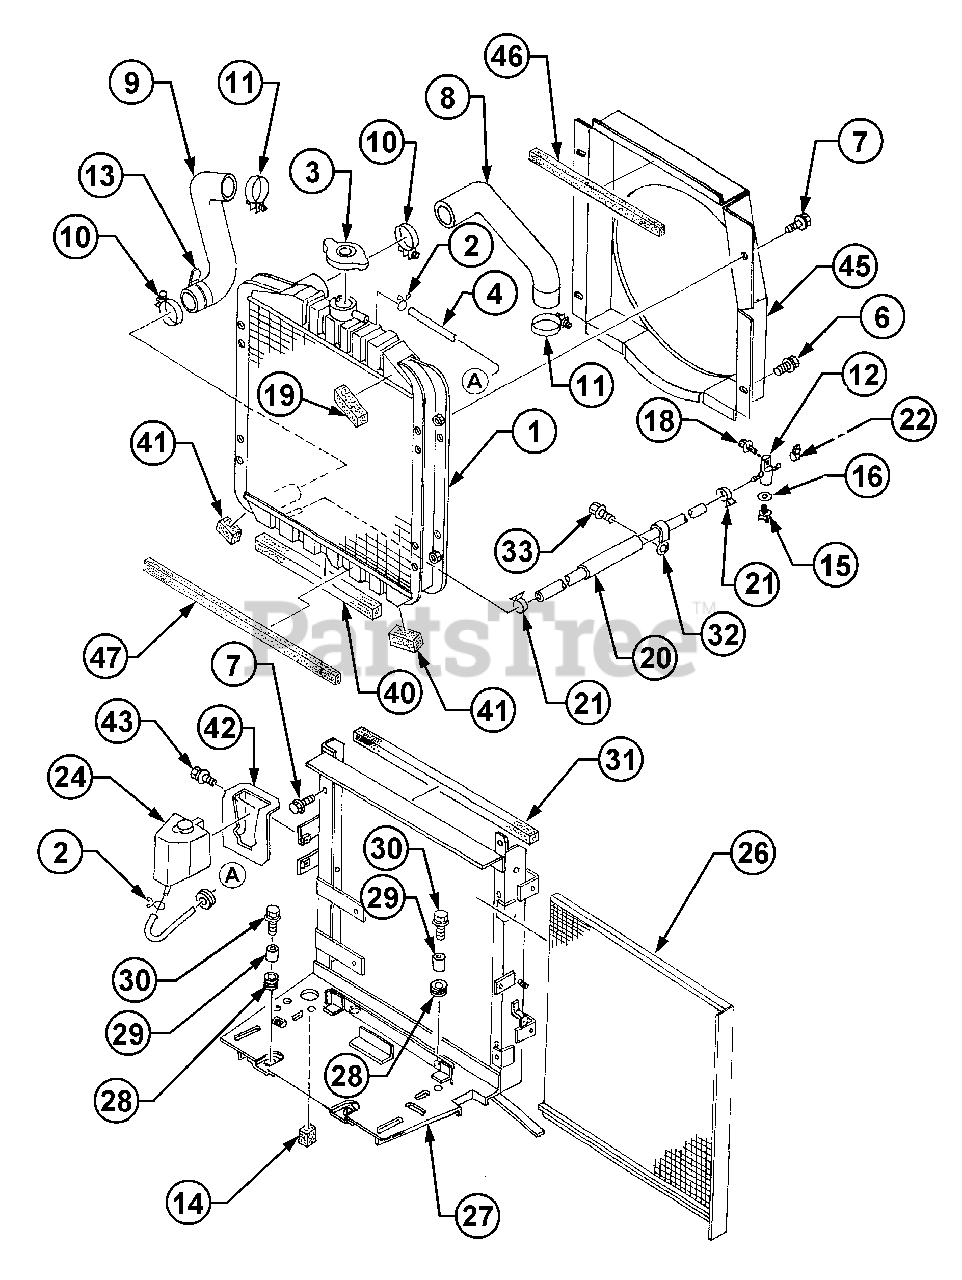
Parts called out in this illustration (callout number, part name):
1	Radiator
6	Bolt, w/Washer
7	Bolt, w/Washer
11	Clamp
15	Cook Water
18	Bolt, w/Washer
24	Sub Tank Assy
26	Net, Radiator
27	Bracket, Battery
30	Bolt, w/Washer
33	Bolt, w/Washer
43	Bolt w/Washer
